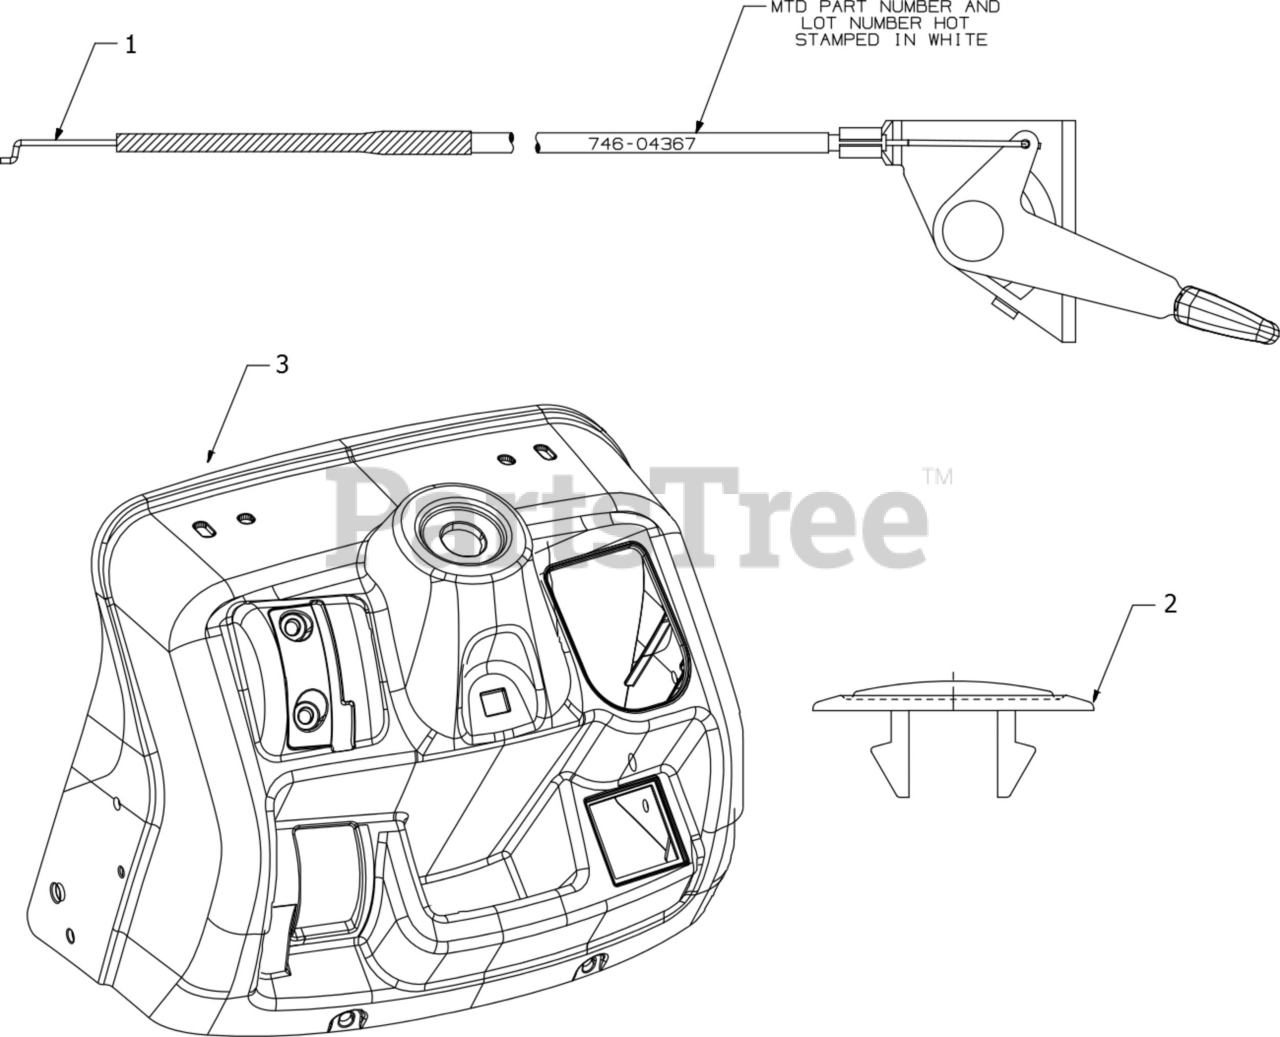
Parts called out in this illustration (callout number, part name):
1	THROTTLE CABLE 28 X 1.1"
2	CHOKE PLUG
3	UPPER DASH
